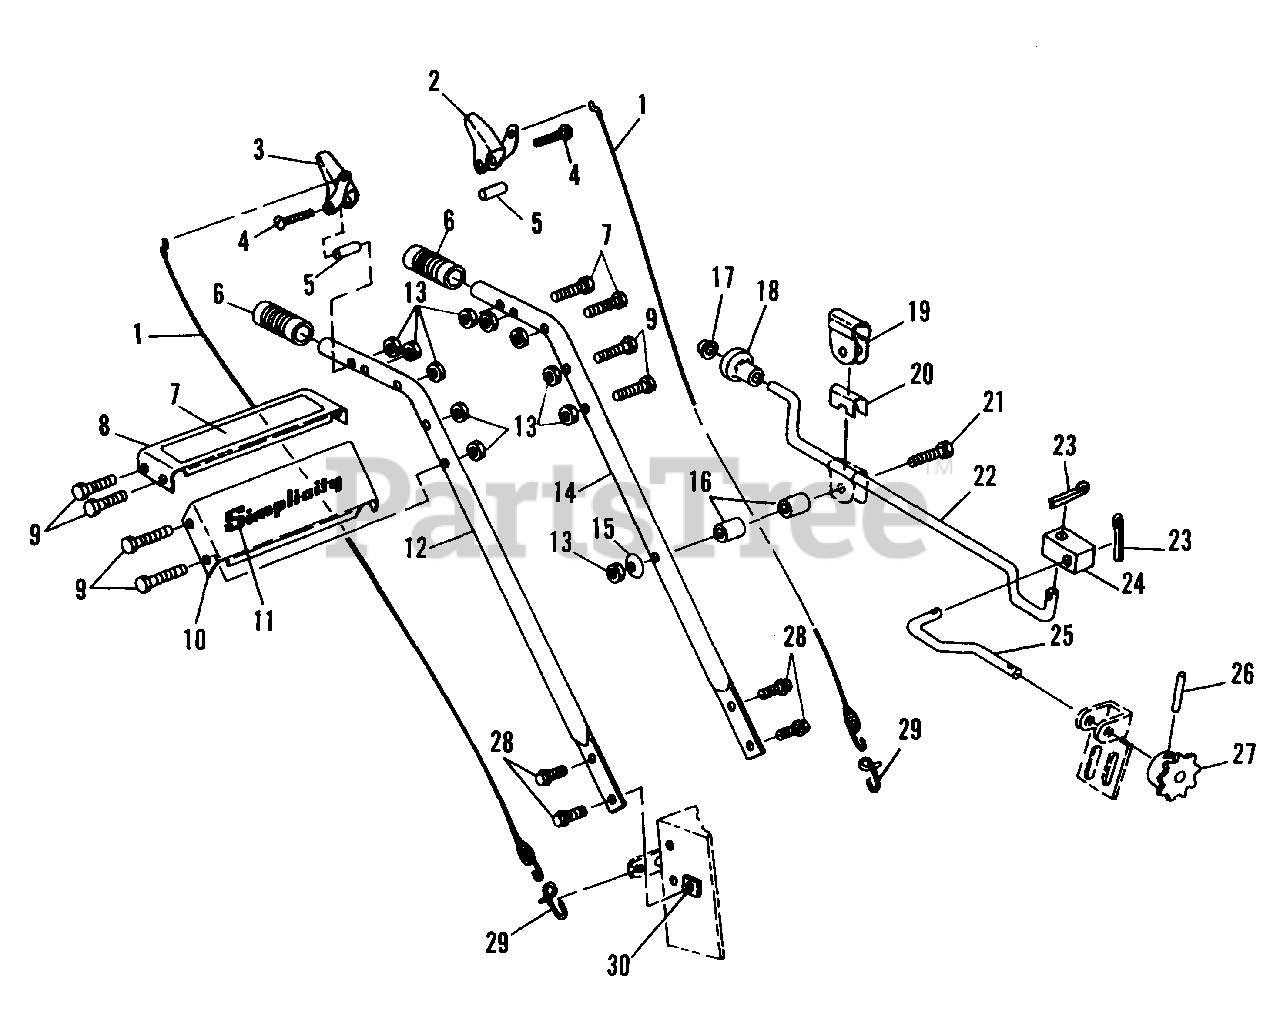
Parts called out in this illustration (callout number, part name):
1	CLUTCH CABLE ASEMBLY
2	CLUTCH LEVER ASEMBLY, LH
3	CLUTCH LEVER ASEMBLY, RH
4	SCREW, Slot,1/4-20 x 1-1/2
7	DECAL, Dash
8	HANDLE PANEL, Upper
9	CAPSCREW, Hex Head, 1/4-20 x 1-1/2
10	HANDLE PANEL, Lower
11	DECAL, Simplicity
12	HANDLE TUBE, RH
13	NUT, Hex Centerlock, 1/4-20
14	HANDLE TUBE, LH
15	FORMED WASHER
17	PALNUT
18	SPINNER KNOB
19	BRACKET, Chute Rod
21	CAPSCREW, Hex Head,1/4-20 x 3
22	CHUTE CONTROL ROD
23	PIN, Cotter
24	PIVOT BLOCK
25	CHUTE ROD-Lower
27	SPROCKET, Chute
28	SCREW, Flange Lock, 5/16-18 x 5/8
29	LINK, Cable
30	NUT RETAINER
